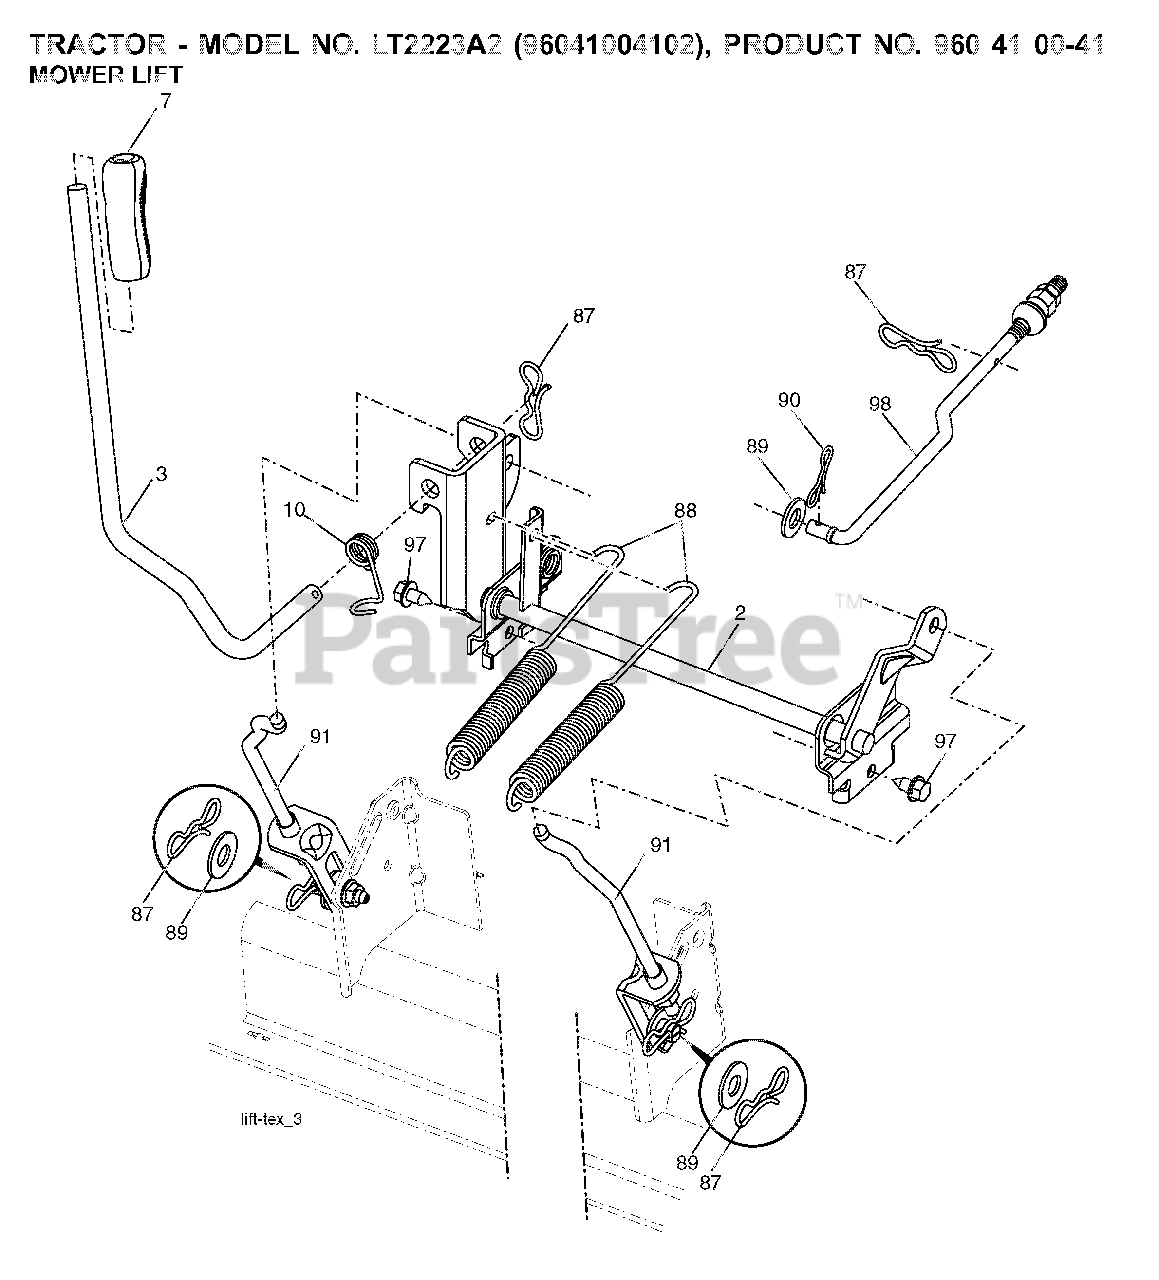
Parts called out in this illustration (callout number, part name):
2	SHAFT.ASM.LIFT.CROSS.H
3	LEVER.LIFT.HANDLE.GT
7	GRIP.HANDLE.LIFT.PVC.BLACK
10	SPRING.TORSION.LIFT.HANDLE
87	PIN.COTTER.7/16.BOW TI
88	SPRING.LIFT.ASSIST.LT
89	WASHER.CLEAR.ZINC
90	PIN.COTTER.5/16.BOW TI
91	LINK.LIFT.ASM.REAR.GT.
97	SCREW, 3/8-16X3/4
98	LINK.ASM.SUSP.FRONT.MWR.10.5
